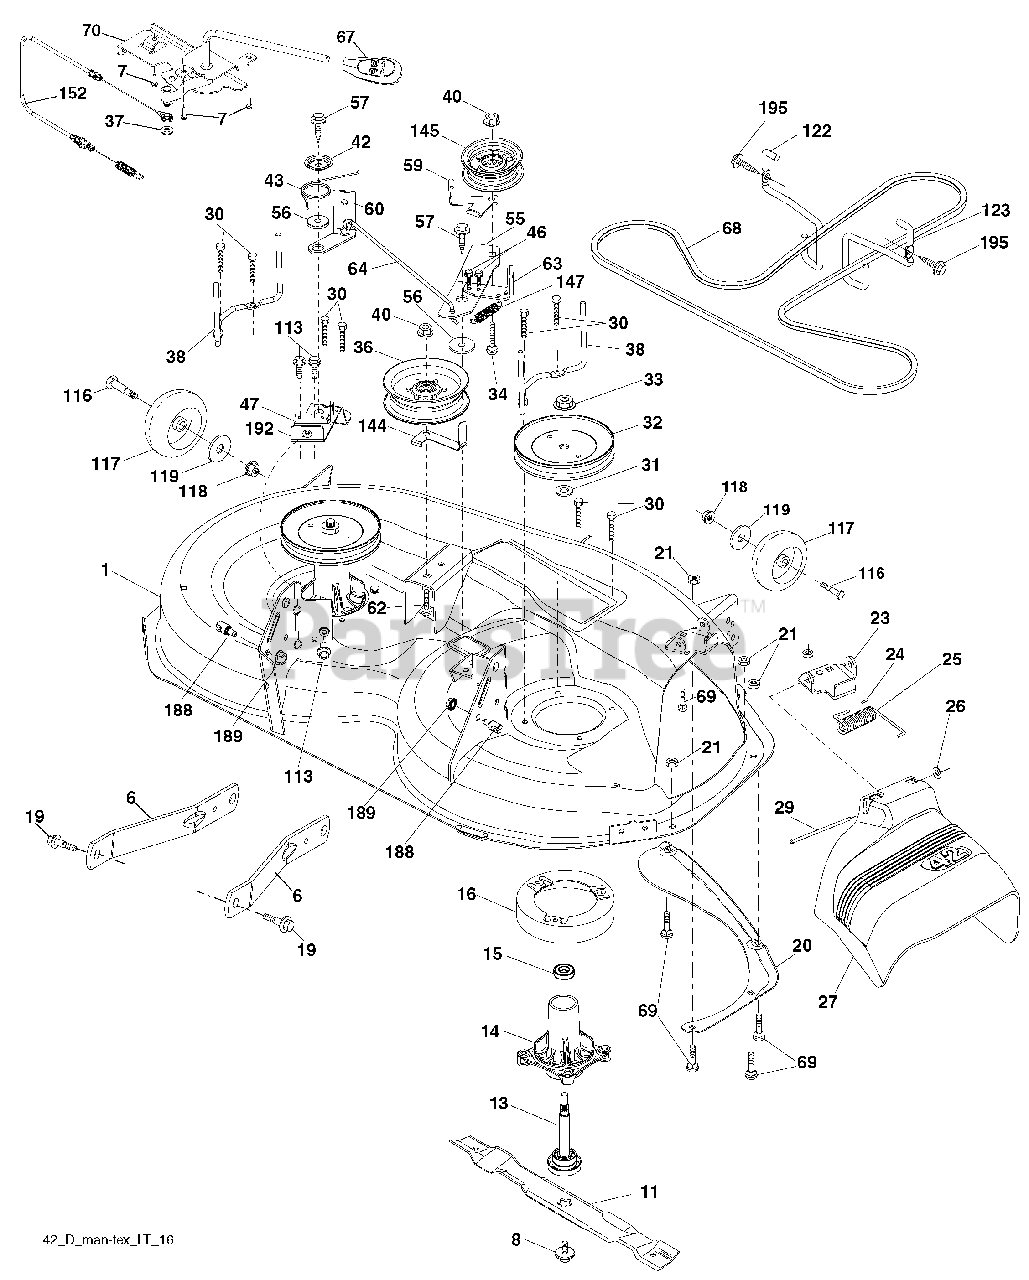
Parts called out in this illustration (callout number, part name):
6	Arm Suspension
7	Screw #10 x 0.750 BOS Thread
8	Bolt/Washer Asm. 7/16-20 unf
8	Blade, 42" Mulching Premium (For better wear when mulching)
11	Blade, 42" Hi-Lift (For bagging or discharge)
11	Blade, 42" Mulching Std. (For mulching mowers only)
13	Shaft Assembly, Mandrel
14	Housing, Mandrel
15	Bearing, Ball, Mandrel
16	Stripper, Mower Deck
19	Bolt, Shoulder
20	Baffle, Vortex
21	Nut, Crownlock 5/16-18 unc
23	Bracket, Deflector
24	Cap, Sleeve
25	Spring, Torsion, Deflector
26	Nut, Push
27	Shield, Deflector
29	Rod, Hinge
30	Screw Thdrol. Rolling Wsh. Hd.
31	Washer, Spacer
32	Pulley, Mandrel
33	Nut, Toplock, Flanged.
34	Bolt Carr. Sh. 3/8-16 x 1-1/2 Gr. 5
36	Pulley, Idler, 4.50 RAW
37	Washer 13/32 x 13/16 x 16 Ga.
38	Keeper Belt LH Mandrel
40	Nut, Lock Flg. 3/8-16 unc
42	Spring Torsion Brake
43	Spring Torsion Retainer
46	Screw Thd. Roll. 1/4-20 x 5/8
47	Bracket Clutch Cable
55	Arm, Idler
56	Spacer, Retainer
57	Screw Hexwsh. Thd. 3/8-16 x 1
59	Guard, Tuv Idler (94)
60	Arm Brake Mower
62	Bolt Rdhd. Sqnk. 3/8-16 unc x 2
63	Arm Brake Mower
64	Linkage Brake
67	Handle, Clutch Cable
68	V-Belt
69	Bolt Rdhd. Sqnk. 5/16-18 x 5/8
70	Clutch Asm. Manual
113	Screw 5/16-18
116	Bolt
117	Wheel Gauge
118	Nut Lock 3/8-16 unc
119	Washer 3/8-7/8 x 14 Ga.
122	Keeper Belt Eng. LH
123	Keeper Belt Eng. RH
144	Keeper Belt
145	Pulley Idler
147	Spring Return
152	Cable Clutch Manual w/Spr.
188	Stud Fastener
189	Nut Lock Hex Flange
192	Bracket Brake Stand LH
195	Screw Hexwsh. Thdr. 3/8-16 x 3/4
195	Mandrel Assembly
195	Replacement Mower, Complete
